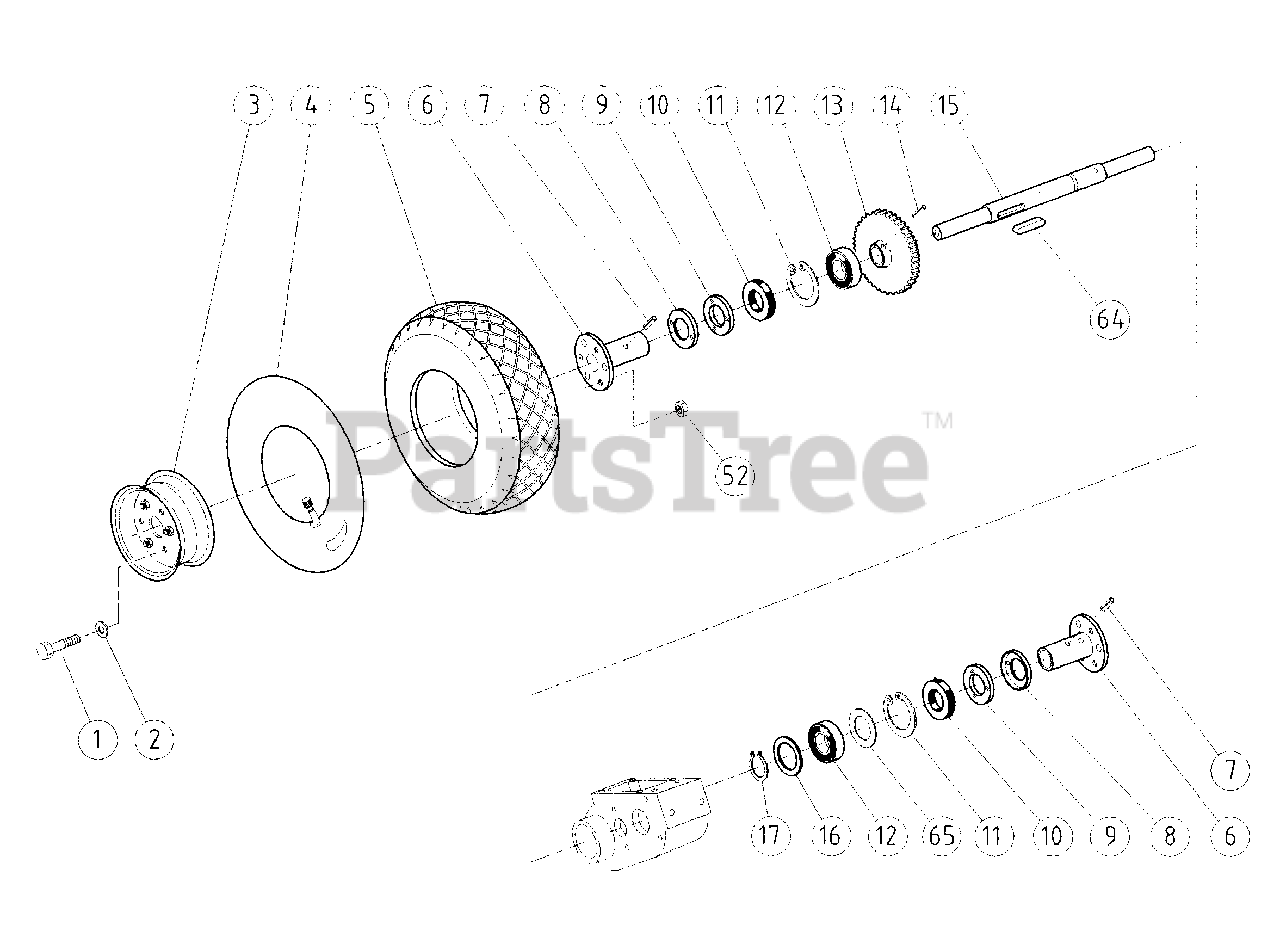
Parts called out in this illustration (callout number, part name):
1	Screwcap M8x16
2	Washer Flat M8
3	Rim Rear wheel
4	Tube Inner Rear Wheel
5	Tire Rear
6	Hub wheel
7	Pin Elastic 10x40
8	Cover Dust
9	Felt protection
10	Ring Seal 25 X 52 X 7
11	Ring Snap Internal 152
12	Bearing 25x52x15 6205
13	Gear Reduction-crown
14	Dowel M8x14
15	Axle Rear
16	Shim adjustment 25x35x1
17	Seeger E25
52	Nut M8 H5
64	Key 7x8x35
65	Shim Adjustment Ø 42x52x0.5
